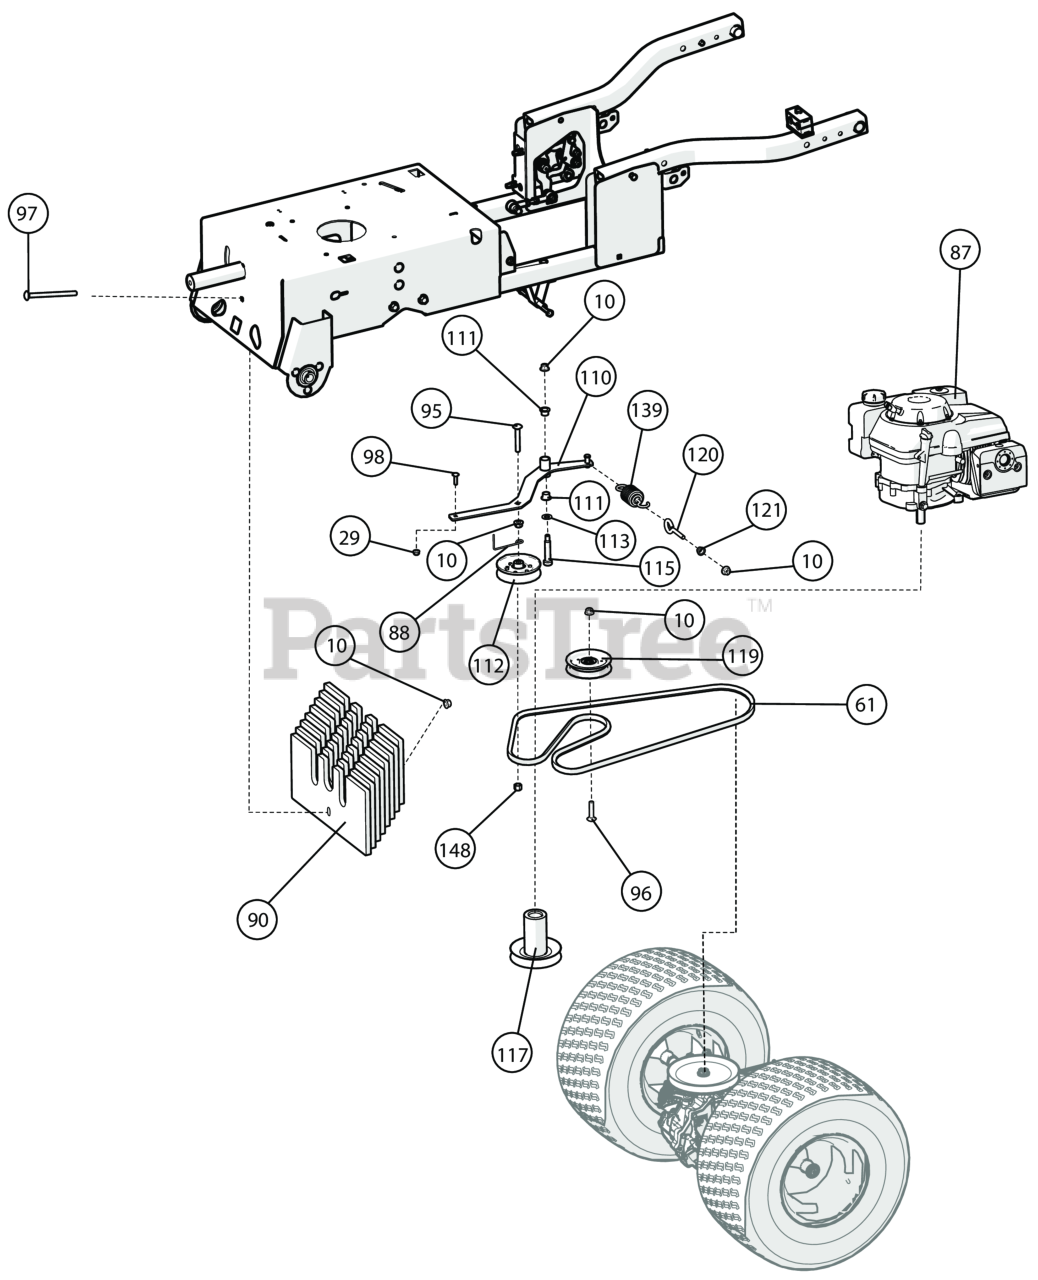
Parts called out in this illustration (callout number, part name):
10	NUT-HEX-NYLK, FLG .375"-16 ZP
29	NUT-HEX-NYLK, FLG .250"-20 ZP
61	BELT, DRIVE
87	ENGINE 13HP HONDA GX390UTQA2
88	BELT FINGER, .375 X 2.875, 90 DEG
90	PLATE, 1/2" WEIGHT
95	BOLT CARRIAGE 3/8-16 X 2 1/2" ZP
96	BOLT CARRIAGE 3/8"-16 X 1 3/4" ZP
97	BOLT CARRIAGE 3/8-16 X 5" ZP
98	BOLT CARRIAGE 1/4"-20 X 1" ZP
110	WA, IDLER
111	BUSHING .500" ID
112	PULLEY IDLER INSIDE 4"
113	WSHR-STL,FLT .500"X.875"X.0747" MAB ZP
115	BLT-SLDR,SH.500"X2.00",.375"-16X.63"G8ZP
117	PULLEY, 4.00"
119	PULLEY IDLER 4" OD X 3/8"
120	BOLT EYE G-2 3/8" X 2"
121	NUT WASHER FACE
139	SPRING-EXT, 1.5ODX4.750LGX.177WR, BLK
148	NUT LOCK 3/8"-16 HEX
